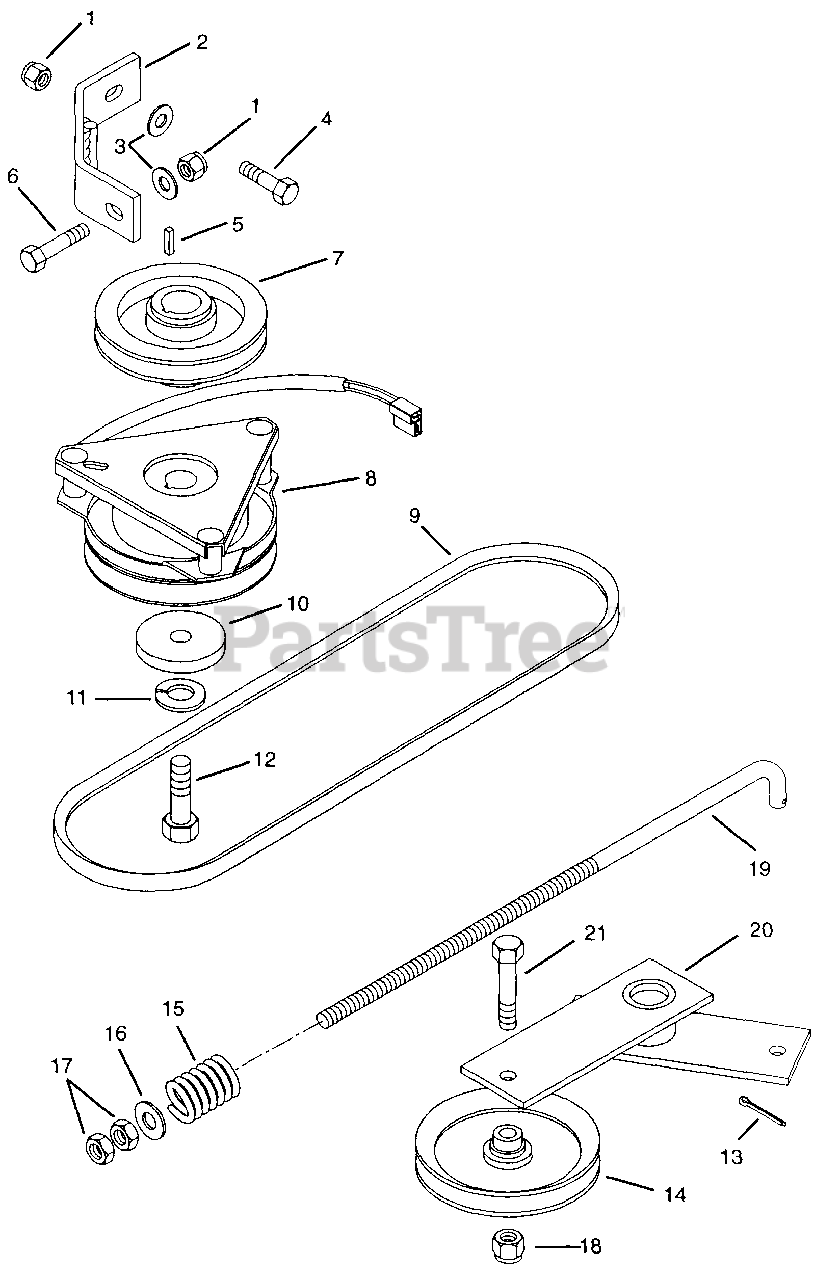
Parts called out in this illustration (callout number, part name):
1	Nut-Locking-Nylon .312-18
2	Weldment, Clutch Stop (007,008)
2	Weldment, Clutch Stop (011)
3	Washer-Flat-Steel .344 x .688 x .065
4	Bolt-Hex .31-18 x 1.00 Grade 5
5	Key-Square .248 x 1.25 x .248
6	Bolt-Hex .31-18 x 1.25 Grade 5
7	Sheave (007,008)
7	Sheave (011)
8	Clutch, Electric (007,008)
8	Clutch, Electric (011)
9	V-Belt A-Section 19.65 x 17/32 (007,008)
9	V-Belt (011)
10	Washer-Special .469 x 2.000 x .250
11	Washer-Lock .44
12	Bolt-Hex .44-20 x 1.50 Grade 5
13	Pin-Cotter .09 x .75
14	Pulley-Idler 4.50 x .380
15	Spring-Compression .072 x .561 x 2.50
16	Washer-Flat-Steel .406 x .812 x .065
17	Nut-Hex .375-16
18	Nut-Locking-Nylon .375-16
19	Rod, Idler
20	Weldment, Idler
21	Bolt-Hex .38-16 x 1.875
